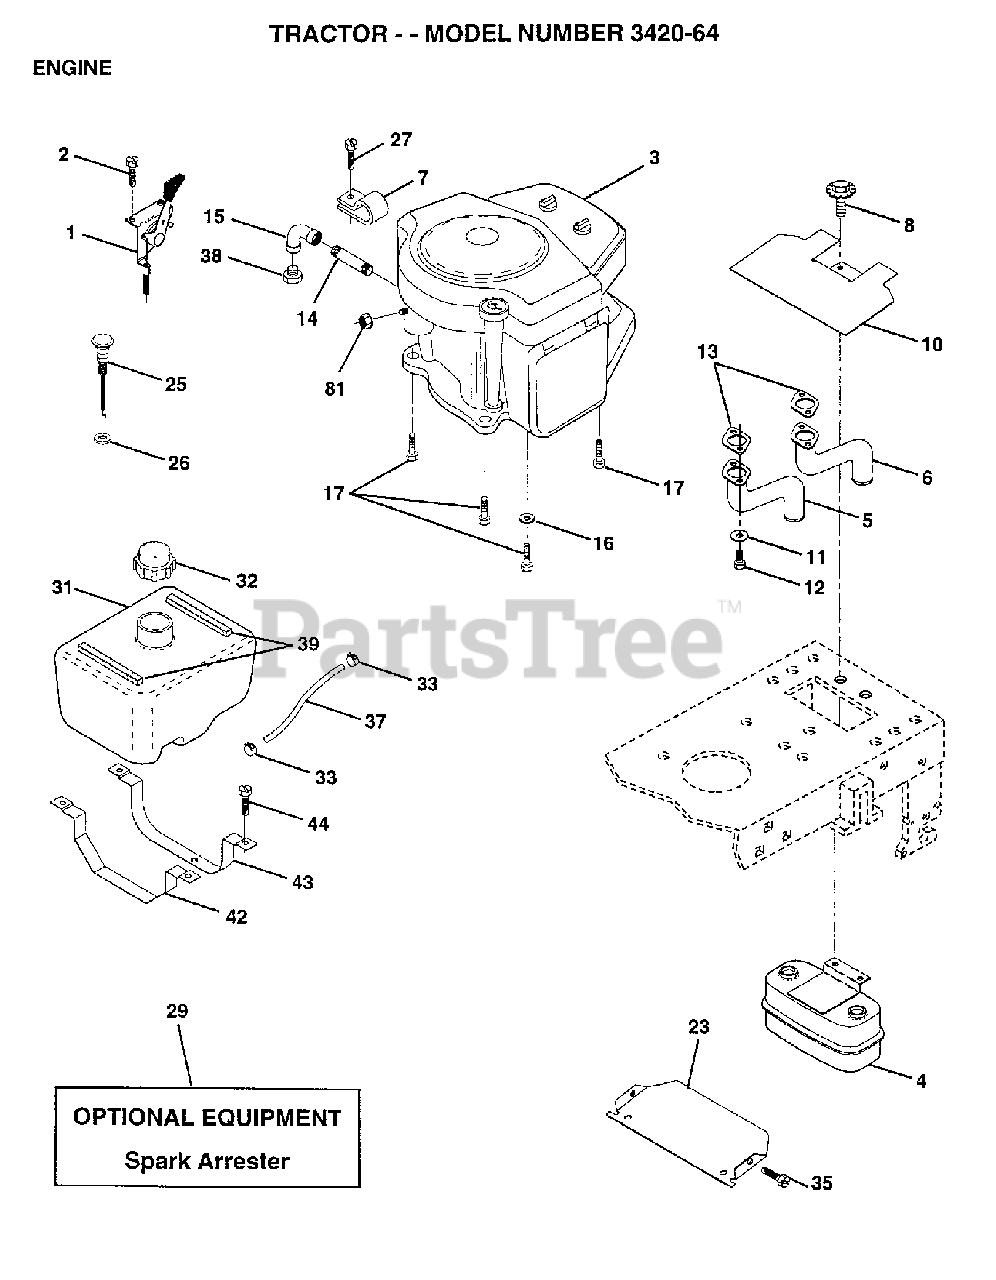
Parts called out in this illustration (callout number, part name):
1	DECK W/DECALS 72" HUS
4	MUFFLER.TWIN.CYL.LOW.TONE
5	EXHAUST ASM. LEFT
6	EXHAUST ASM. RIGHT
10	SHIELD HEAT LT
11	LOCKWASHER
13	GASKET (B&S 692282)
14	NIPPLE, PIPE 3/8NPT X 4-1/2
15	ELBOW
16	LOCKWASHER
25	CONTROL.CHOKE.51.00.BLK.W/BEND
26	NUT KEPS 3/8 - 24 UNF
27	SCREW.TT.#10-32X.5.3/8.FLANGE
29	KIT.SPARK ARRESTOR(392390 B&S)
33	HOSE CLAMP
35	Screw, Lt
37	LINE FUEL 7.5"
